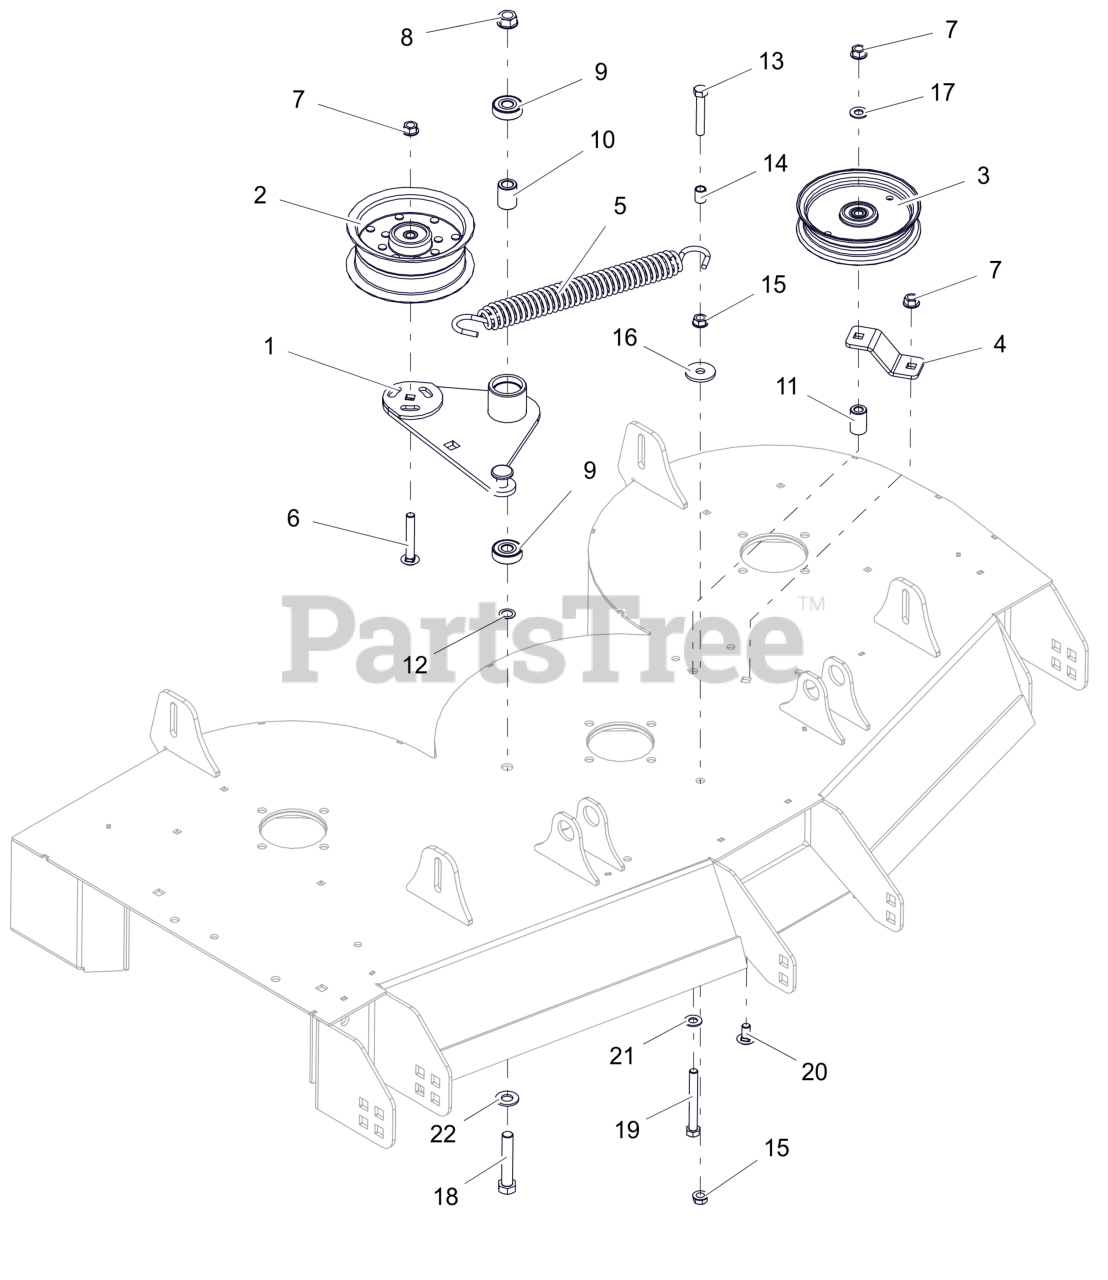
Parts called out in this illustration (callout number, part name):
1	WLDMT- IDLER ARM
2	PULLEY, FLAT 5.00X2.36X.375
3	IDLER- FLAT - 5.00" X .75"
4	PTO FIXED IDLER MTG BRKT -RED
5	SPRING, EXTENSION
6	BLT, RHSSN.38-16X2.50 G5 ZCC
7	NUT-LK-CTR-FLG .375-16 GF ZCC
8	NUT-LK-CTR-FLG .500-13 GG ZCC
9	BRG-BALL .500X1.38X.437
10	SPACER .510 X .867 X 1.1485
11	BUSHING, SLV .380X.750X1.190
12	WASHER, .500X.750X.020 THRUST
13	BLT,HEX .38-16X2.25 G5 ZCC
14	SPCR, SLV .385X.500X.652
15	NUT, SPNLK-FLG .38-16 G5 ZCC
16	WSHR,FLT .406X1.375X.135 ZCC
17	WSHR,FLT .406X.812X.065 ZCC
18	BLT,HEX .50-13X2.75 G5 ZCC
19	BLT, HEX .38-16X3.25 G5 ZCC
20	BLT, RHSSN .38-16X.75 G5 ZCC
21	WSHR,FLT .406X.812X.065 ZCC
22	WSHR,FLT .531X1.062X.095 ZCC
